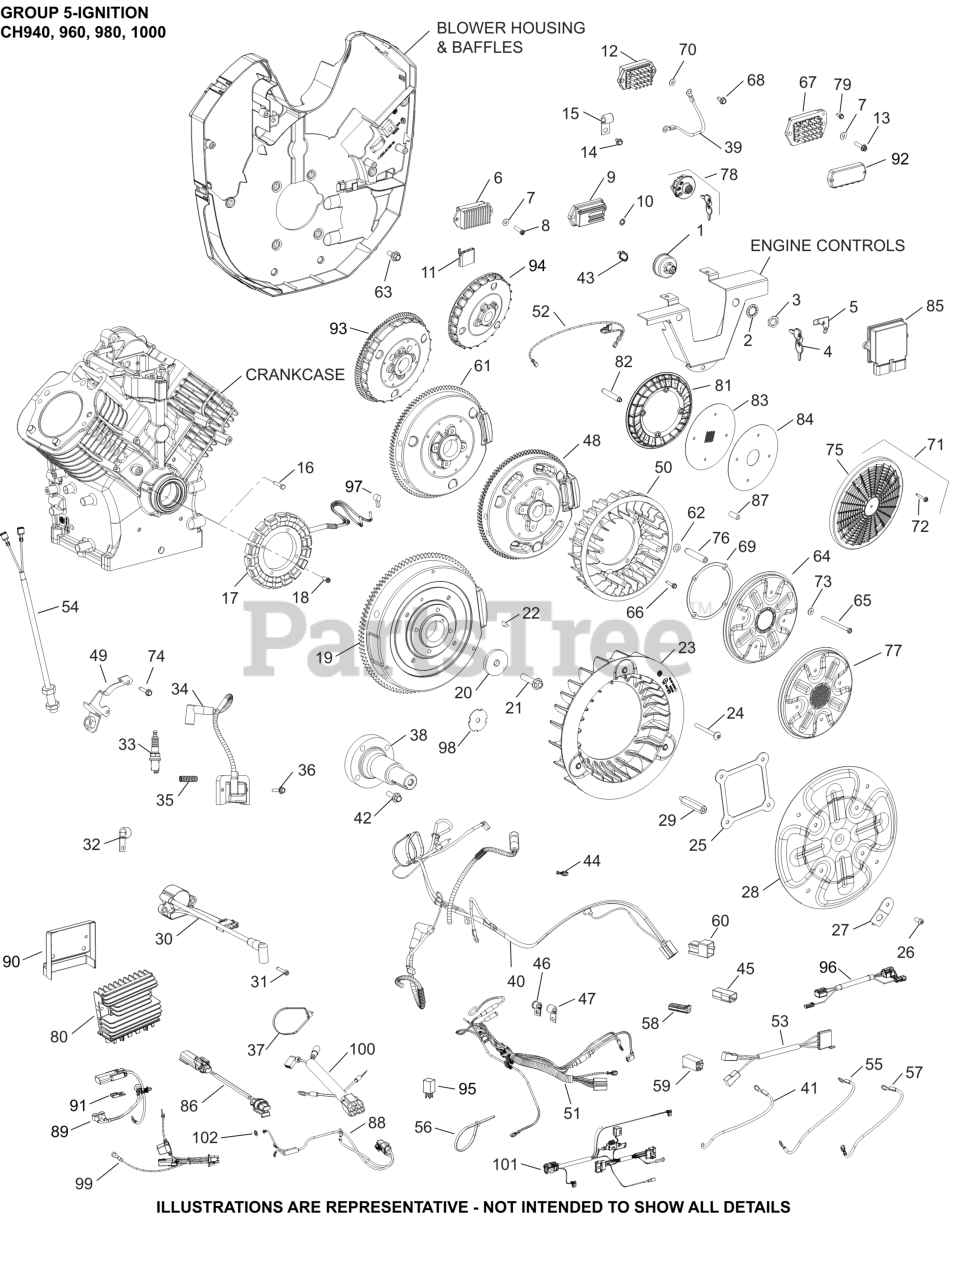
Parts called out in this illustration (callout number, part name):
11	CONNECTOR
13	SCREW, HEX FLANGE HI-LO
14	SCREW, FLG THD FRM M5X.8X10
18	SCREW, THREAD FORMING
20	WASHER, FLAT 13/32"
22	KEY, 3/16" X 5/8"
23	FAN-(#6215706S)
28	SCREEN, GRASS
32	CLIP, CABLE
32	CLIP, CABLE (KM)
33	PLUG, SPARK
37	TIE, CABLE
38	SHAFT, FRONT DRIVE
39	KIT, GROUND, LEAD
41	LEAD, B+ TO STARTER SOLENOID
42	SCREW, HEX FLANGE
43	CLIP, CABLE-DISCONTINUED
54	SENSOR, MAGNETIC
61	FLYWHEEL, ASSEMBLY
62	WASHER, SPRING 10 MM
65	SCREW, HEX HEAD
66	SCREW, THREAD THROWING
67	REGULATOR, RECT (20-30AMP, FW W/OVP)
68	SCREW, THREAD FORMING
69	RING, SUPPORT
73	WASHER, FLAT 1/4" (O.D. 5/8")
76	SPACER, GRASS SCREEN
79	SCREW, THREAD FORMING
NI	KIT, 25AMP STATOR
NI	SCREW, HEX FLANGE
NI	HARNESS, WIRING (KEY SWITCH)
NI	MODULE, IGNITION
